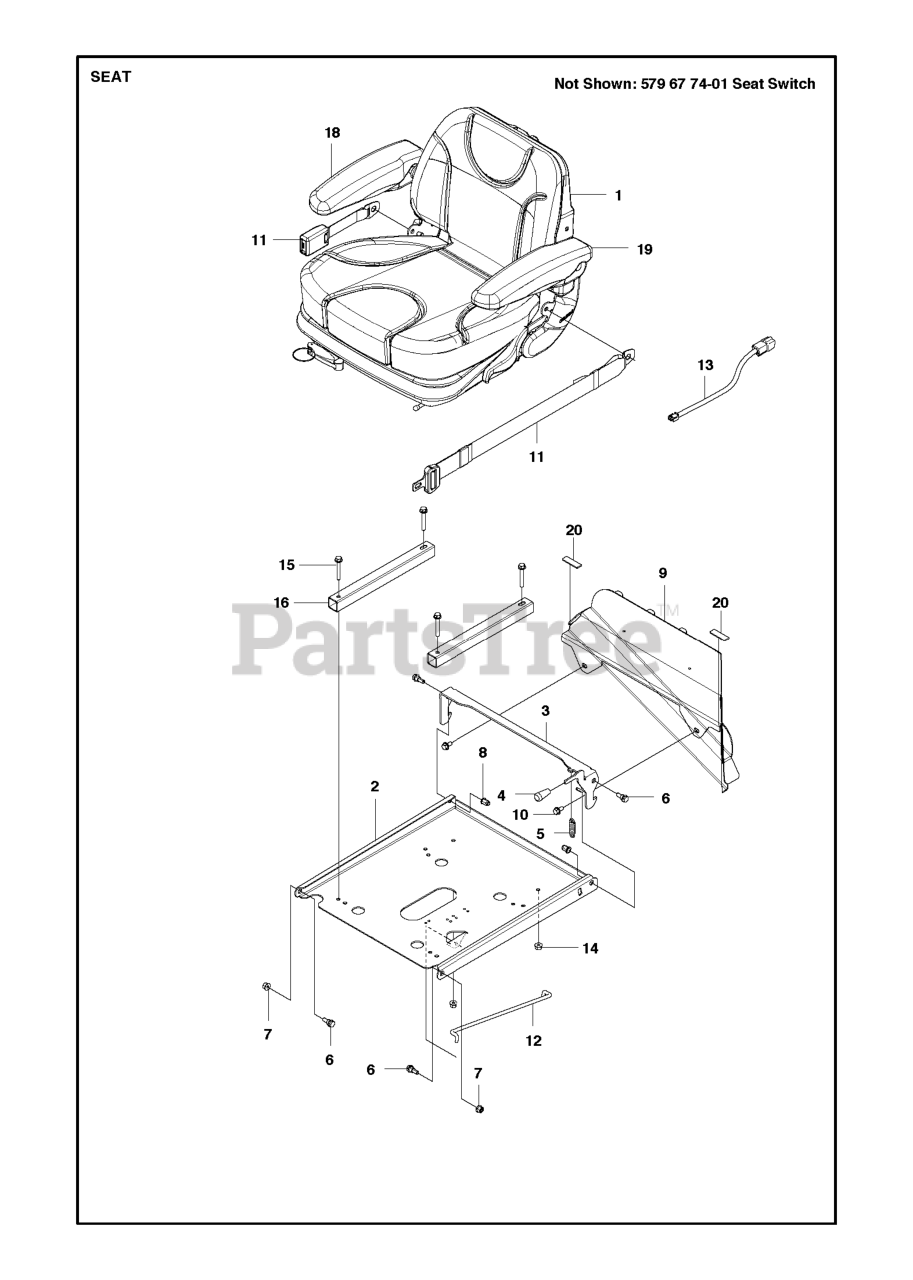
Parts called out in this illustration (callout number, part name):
5	DRAW SPRING L=50
7	NUT FLANGE
14	NUT FLANGE
14	5/16-18 NYLOC FLANGE NUT
15	SCREW EHHFM
